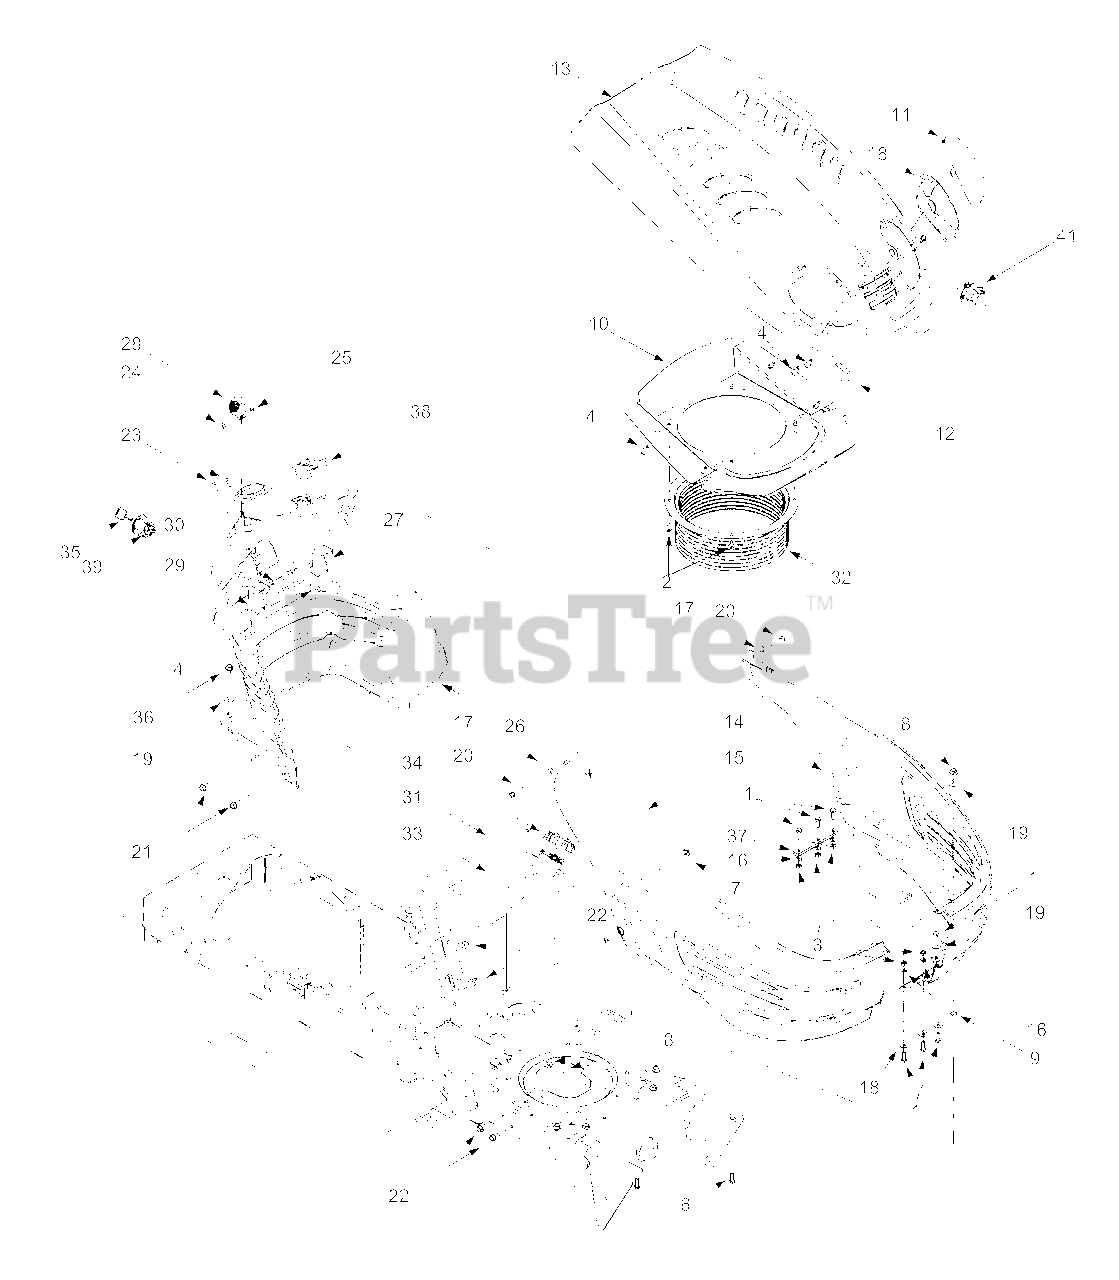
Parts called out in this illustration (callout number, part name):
1	Hex Cap Screw, 1/4-20 x .75
2	Self-tapping Screw, 1/4-20 x .5
3	Hex Nut, 1/4-20
4	Self-tapping Screw, 1/4-15 x .75
6	Hex Cap Screw, 5/16-18 x 1.0
7	U-type Speed Nut, 1/4-20
8	Flange Lock Nut, 5/16-18
9	Speed Nut
11	RH Headlight Lens
12	Hood Support Rod
13	Hood
14	LH Side Panel
15	RH Side Panel
16	Lock Washer, 1/4
17	Flat Washer, .283 x .75 x .030
18	RH Headlight Reflector
19	Flat Washer, .349 x 1.0 x .063
20	Self-tapping Screw, 1/4-20 x 1.25
21	Self-tapping Screw, 5/16-18 x .75
22	Self-tapping Screw, 5/16-18 x .625
23	Torx Self-tapping Screw, 1/4-14 x .625
24	Torx Screw, #8-32 x .375
25	Hex Nut, 8-32
26	Dash Panel
27	Parking Brake Button
28	Throttle Control Lever
29	Cruise Control Button
30	Brake/Cruise Pivot Rod
33	Fuel Tank, 3-gallon
34	Fuel Cap
35	Ignition Key w/ plastic cover
36	Self-tapping Screw, 5/16-18 x .75
39	Ignition Switch
41	Lamp-12V-Miniature
